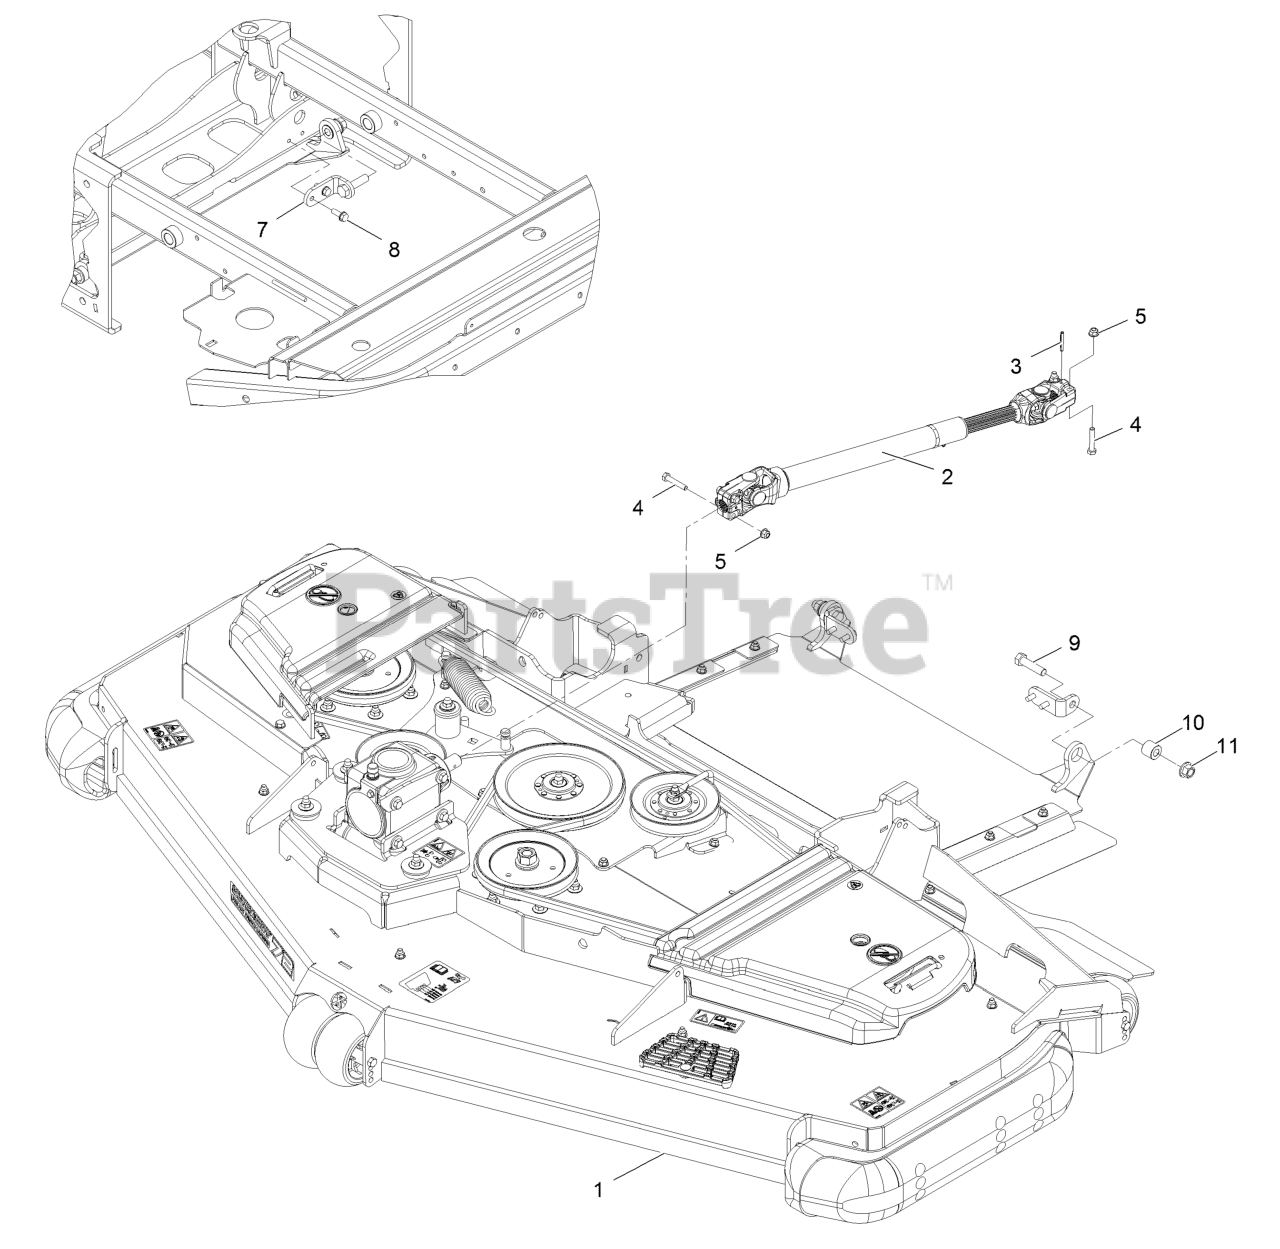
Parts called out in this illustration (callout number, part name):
1	Deck ASM-72Rd
2	Driveshaft ASM
3	Pin-Roll
4	Screw-HH 5/16-18 X 1 3/4
5	Nut-Nyloc 5/16-18 Flg
7	Bracket-Discharge
8	Screw-HWH 3/8-16 X 7/8 Taptite
9	Screw-HH 1/2-13 X 1 1/4
10	Bushing-Sleeve
11	Nut-Lock 1/2-13
